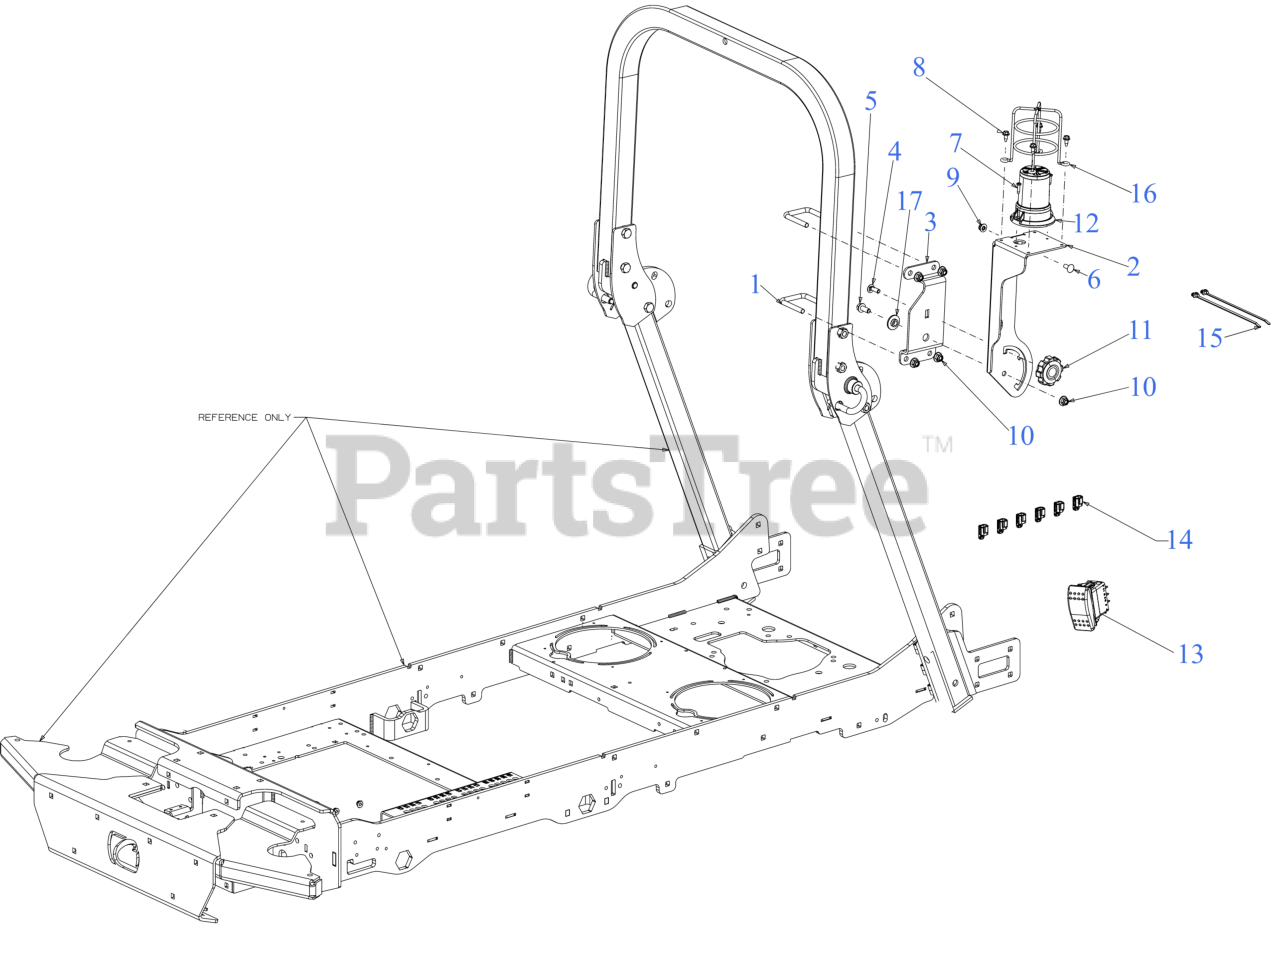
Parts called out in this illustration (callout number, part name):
1	U-BOLT, 3/8-16 X
2	PIVOT MOUNT BRACKET
3	FIXED MOUNT BRACKET
4	CARRIAGE BOLT 5/16-18 x 1.00
5	SCREW 3/8-16 x .875 GR5
6	CARRIAGE BOLT 5/16-18 x .75
7	SCREW (10-24X.75:PH:TAP:T25:GR5)
8	SCREW 1/4-20X.625
9	FLANGE LOCK NUT 5/16-18
11	KNOB-5/16-18
12	LED BEACON LIGHT
13	ROCKER SWITCH
15	CABLE TIE
16	BEACON LIGHT COVER
17	SHOULDER SPACER
